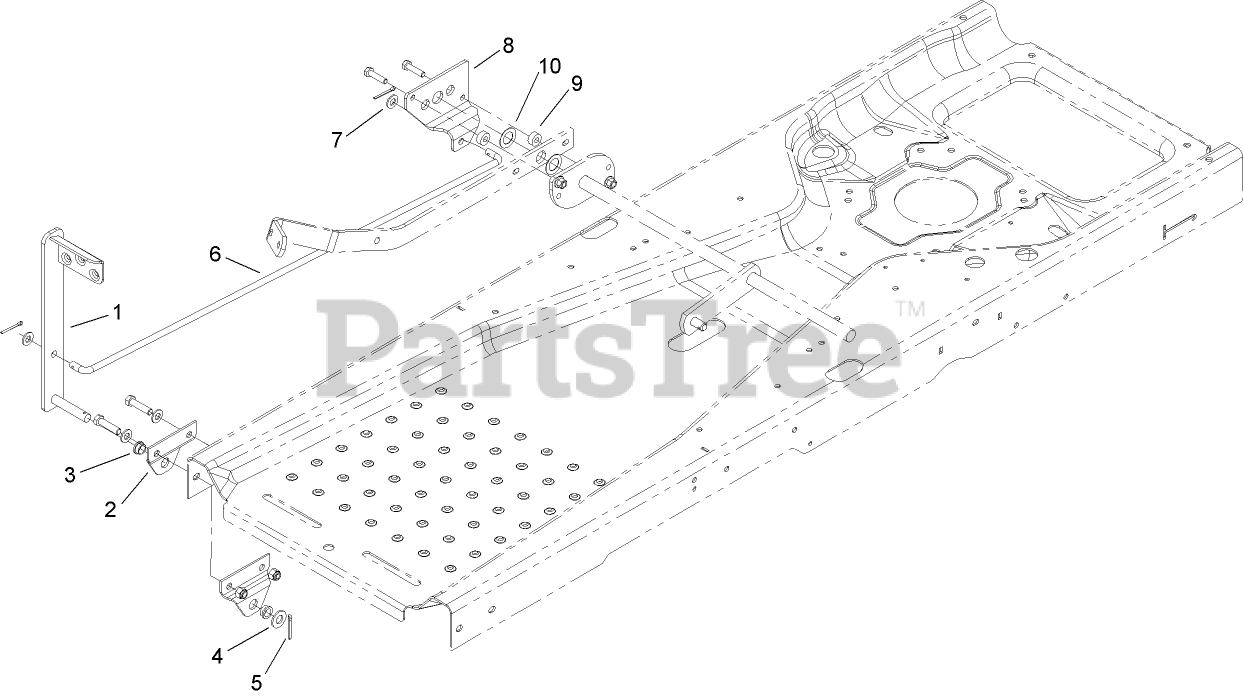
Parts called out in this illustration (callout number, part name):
1	PEDAL ASM
2	BRACKET-FOOTLIFT
3	BUSHING-FLANGE
4	WASHER-FLAT
5	PIN-COTTER
6	ROD-LIFT
7	WASHER-FLAT
8	PLATE-FOOTLIFT
9	SPACER
10	WASHER-THRUST
